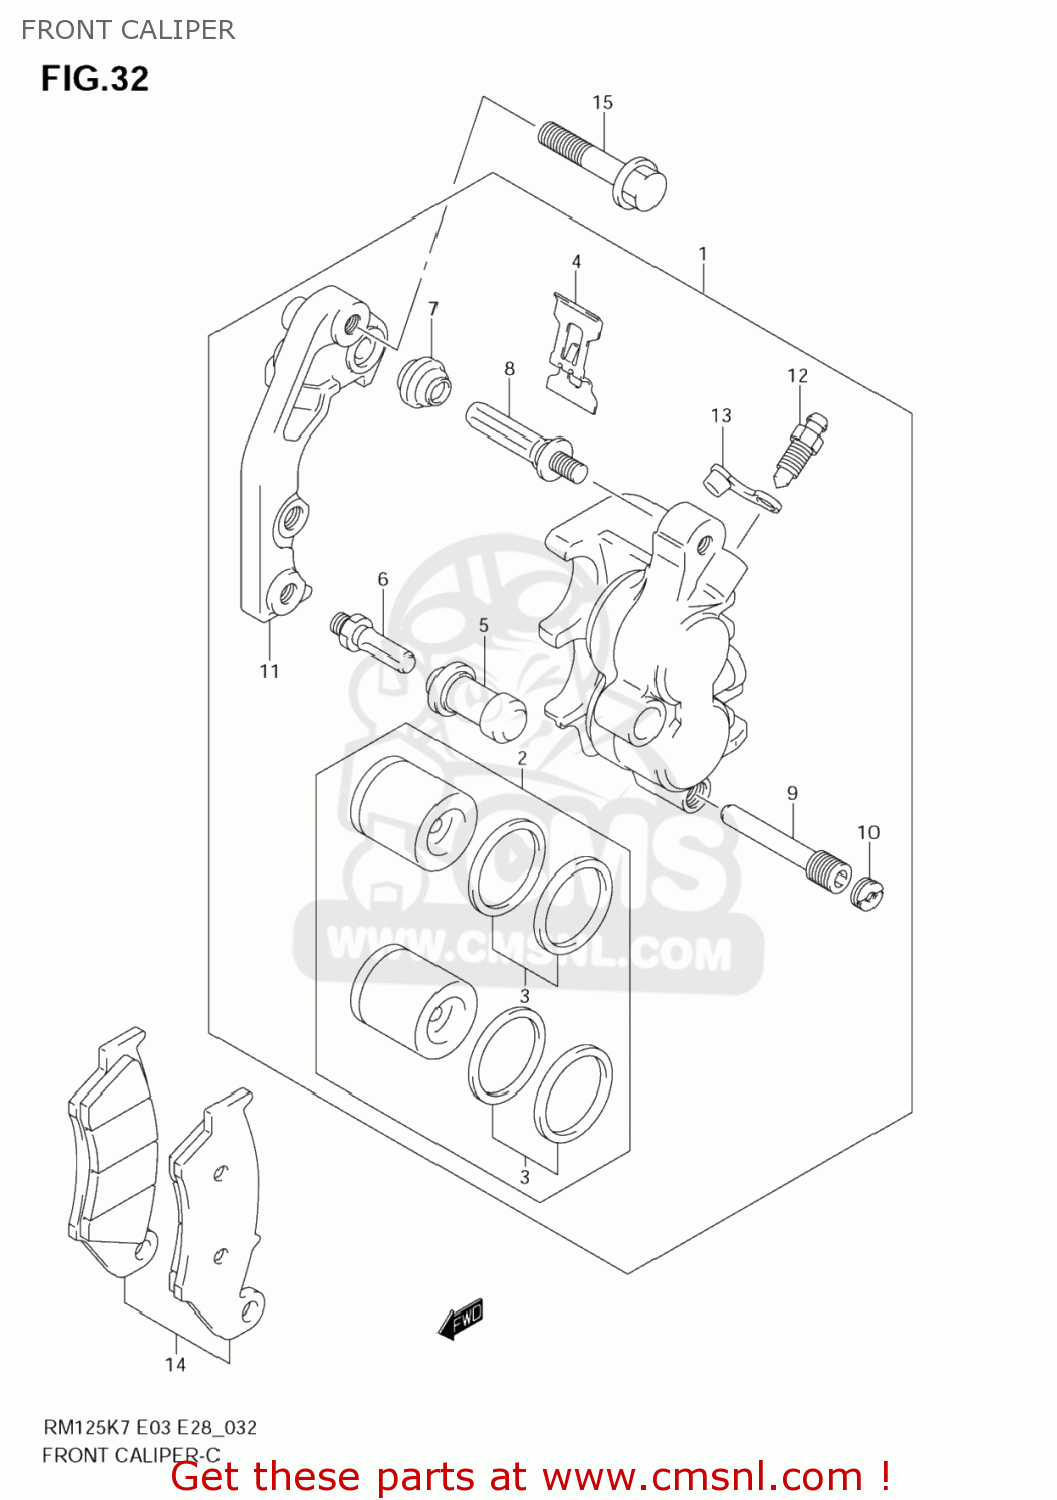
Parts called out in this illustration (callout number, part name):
1	CALIPER ASSY,F
2	PISTON SET
3	SEAL SET,PISTON
4	SPRING,PAD
5	BOOT
6	BOLT
7	BOOT
8	PIN
9	PIN,HANGER
10	PLUG,PIN
11	BRACKET
12	BLEEDER
13	CAP,BLEEDER
14	PAD SET (NAS)
15	BOLT(8X41)
